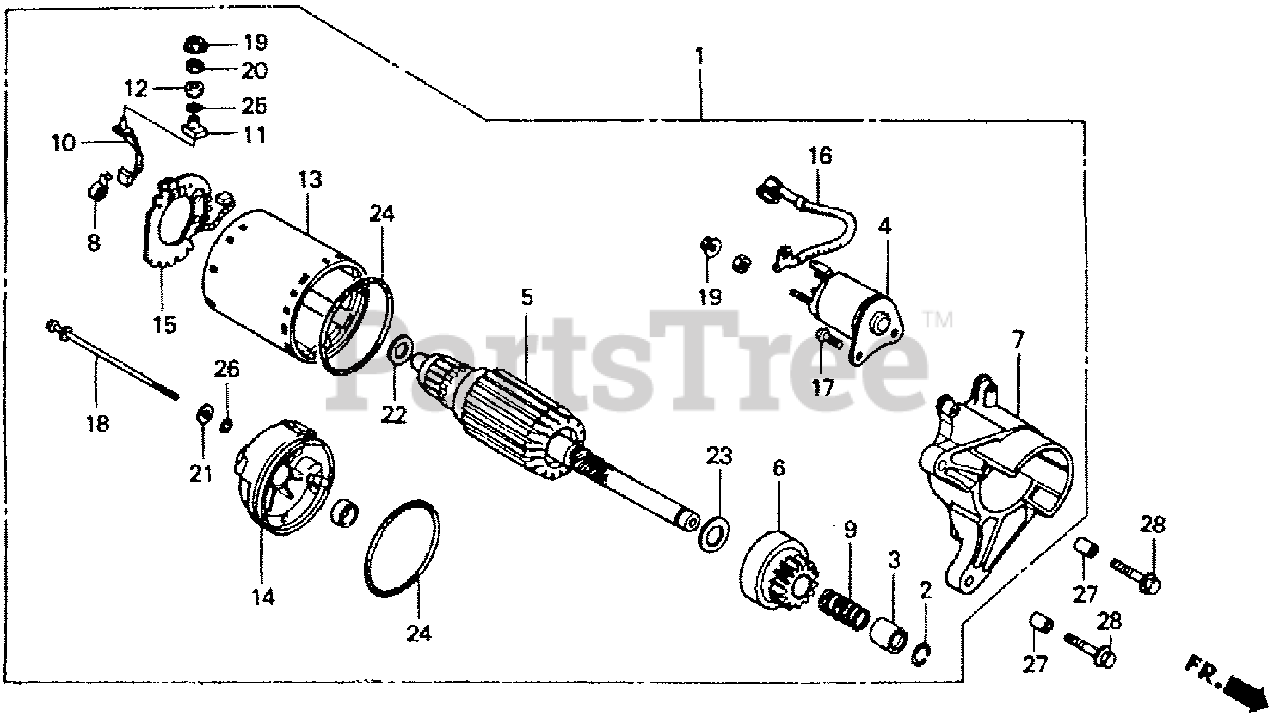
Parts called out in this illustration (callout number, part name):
1	MOTOR ASSY., STARTER
2	RING, SNAP
3	COLLAR, CLUTCH
4	CONTACTOR ASSY.
5	ARMATURE
6	CLUTCH, OVERRUNNING
7	HOUSING, DRIVE SIDE
8	SPRING, BRUSH
9	SPRING
10	BRUSH
11	BUSHING, INSULATION
12	BUSHING, INSULATION
13	YOKE
14	FRAME, STARTER END
15	PLATE, BRUSH HOLDER
16	WIRE, WATER COVER
17	BOLT
18	BOLT, THROUGH
19	NUT
20	NUT
21	WASHER, STEEL PLATE
22	WASHER
23	WASHER
24	O-RING
25	O-RING
26	O-RING
27	PIN A, DOWEL (10X16)
28	BOLT, FLANGE (8X35)
